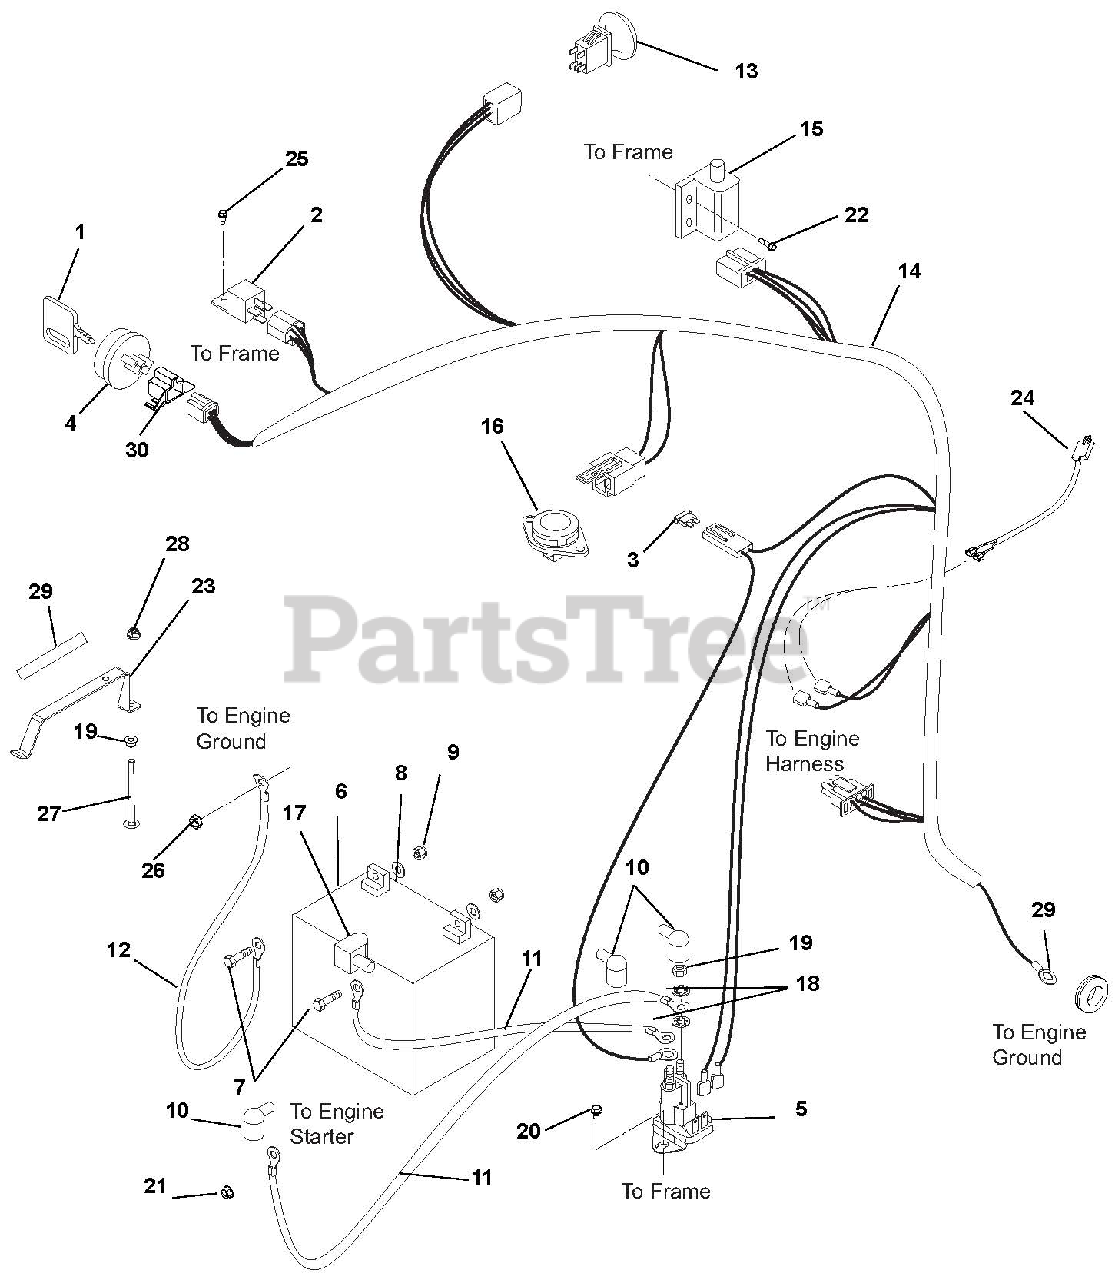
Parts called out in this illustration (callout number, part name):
1	KEY, 03290500 KEYSWITCH
1	KEY -W/CAP
2	RELAY
3	FUSE-25 AMP ATC TYPE
4	KEYSWITCH-IGNITION 3 POS
4	KEY SWITCH
5	SOLENOID, STARTER (SEALED)
6	BATTERY, 12V 12A-190CCA
7	@BLT-HEX .25-20X.75 GR5 YWZC
8	@WSHR-FL-STL.281X.62X.065 YWZC
9	NUT-KEPS .250-20
10	BOOT, EYELET TERMINAL
11	CABLE,POS W/2 1/4 RING 15.0 LG
12	CABLE, NEGATIVE 26" 6 GA.
13	SWITCH, CLUTCH (YELLOW)
14	HARNESS, ZOOM/ZT WIRE
15	SWITCH- DOUBLE POLE N.O./N.O.
16	SWITCH- SEAT
17	INSULATOR
18	@WSHR-LK-EXT.262X.502X.026YWZC
19	@NUT-LK-CTR .31-18 YWZC
20	@SCR-TAP .25-20X.37 HWH YWZ TR
21	@NUT-LK-TOP-FLG .25-20 YWZC
22	SCR- 12-14X.75 HX W/HD TEK ZC
23	HOLDDOWN, BATTERY, U1&190CCA
24	HARNESS, CLUTCH
25	@SCR-TAP 10-24X.50 HWH TR YWZC
26	@NUT-LK-CTR-JAM .375-16 YWZC
27	@BLT-RDHDSQNK .25-20X4.50 G2YZ
28	@NUT-LK-NYL-FLG .25-20 YWZC
29	CABLE TIE LG 5-1/2
30	WIRE HARNESS, KEY SWITCH ADAPT
